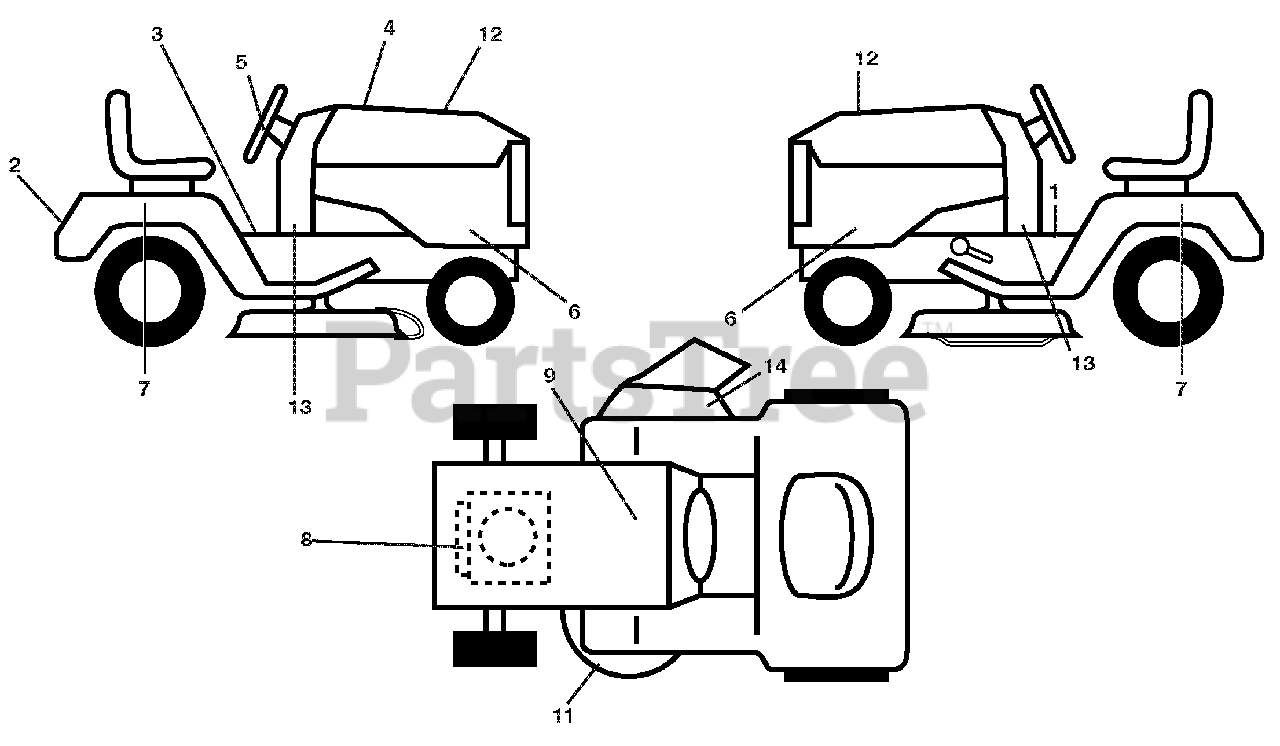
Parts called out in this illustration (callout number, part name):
1	DECAL.WARNING.START
2	DECAL.FENDER.REAR.ARIENS
3	DECAL.FENDER
4	DECAL.REPLACEMENT
5	DECAL.WHEEL.STEER.ARIENS
6	DECAL.SDPNL.PWRDBY B&S.ARIENS
7	DECAL.FENDER.SIDE.HYDRO
8	DECAL.ENGINE.HP
9	DECAL.BAT.DAN/POI P/L SYM.WPN
11	DECAL.V-BELT.SCH.
12	DECAL.HOOD.LH/RH.
13	DECAL.LOWER.DASH
14	DECAL.WARNING.KEEP.HAND.AWY
